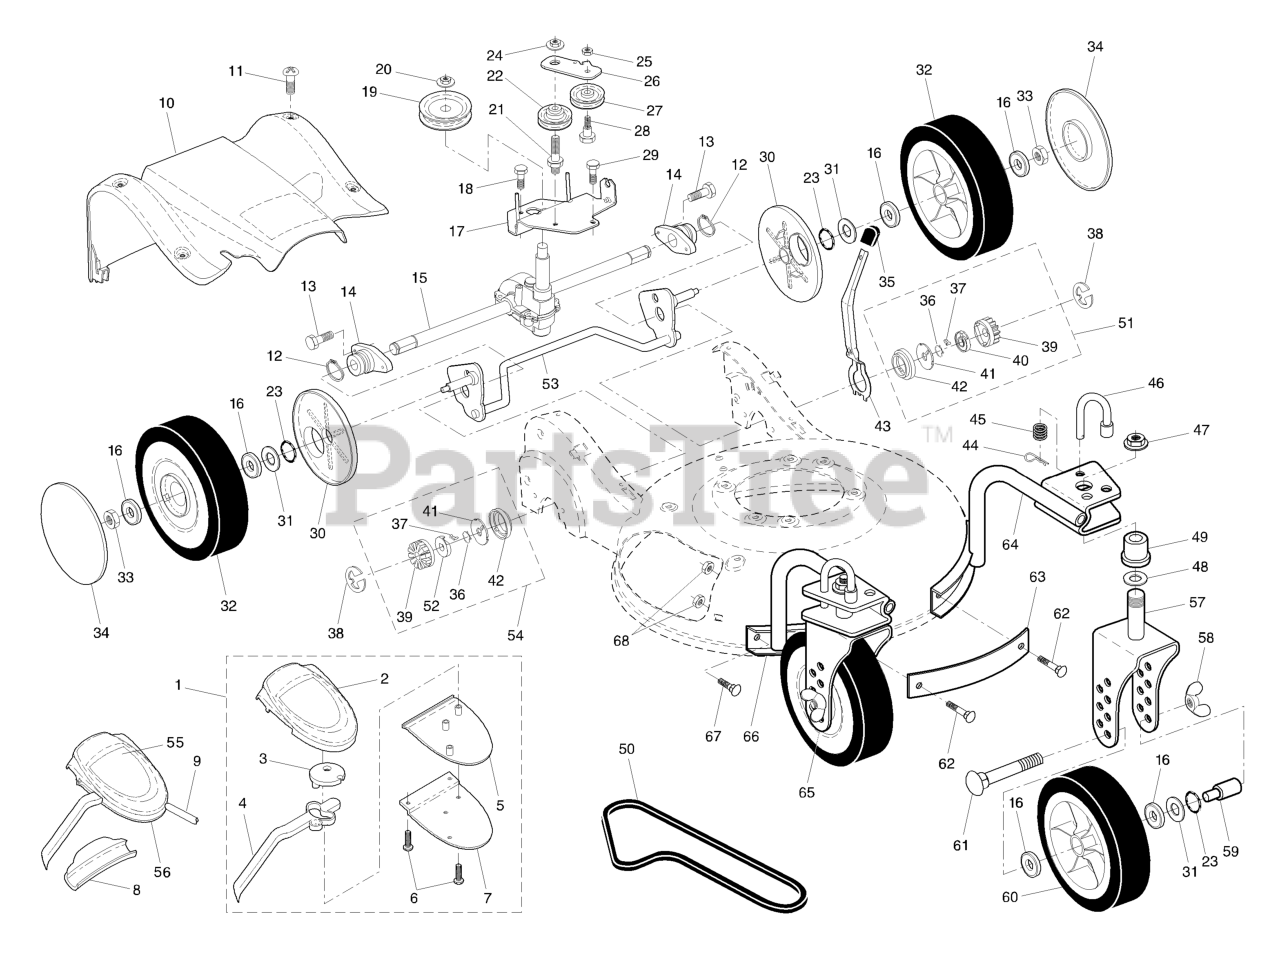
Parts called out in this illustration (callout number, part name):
1	EZ WALK CONTROL
2	COVER, DRIVE CONTROL, TOP
3	PULLEY.CAM.DRIVE.CONTROL.HV
4	LEVER, DRIVE CONTROL
5	COVER, DRIVE CONTROL BOTTOM
6	SCREW, PHILLIPS HEAD 10 X 5/8
7	BRACKET, DRIVE CONTROL
8	EZ WALK SNAP COVER PLATE
9	CABLE, DRIVE CONTROL
10	COVER, REAR DRIVE
11	SCREW
12	RETAINING RING (2 2)(3 2)
13	RP SCREW
14	BEARING.SUPPORT.ASSEM
15	TRANSMISSION.ASM.RGD.EZ.21
16	BEARING.8".WHEEL
17	BRACKET, TRANSMISSION
19	PULLEY HALVES
20	FLANGED LOCKNUT 3/8-16 ZINC
22	PULLEY ASSY
23	O-RING
24	NUT
25	NUT.CENTERLOCK.5/16-
26	BRACKET
27	IDLER PULLEY
28	SHOULDER BOLT
29	SCREW 14-20 X 5/8
30	DUST COVER, WHEEL
31	WASHER.FLAT.1/2
32	WHEEL 9X2.25
33	HEX FLANGE LOCKNT
34	RB HUBCAP.3-SPOKE.SILVER
35	KNOB.SELECTOR.SPRG.H-GRY (2 2)
36	SPRING, TORSION
37	PAWL.DRIVE.21.EZ-WALK
38	E-RING 7/16 RE
39	GEAR, PINION
40	RETAINER.DRIVE.21.EZ-WALK.LT
41	DISC.DRIVE.21.EZ-WALK
42	SEAL.PINION
43	LEVER, SELECTOR
48	WASHER STEEL
49	BUSHING
50	BELT.DRIVE.EZ.WALK.HI-VAC
51	PINION ASSY, LH
52	RETAINER, DRIVE, RH
53	REAR AXLE ASSY.
54	PINION ASSY, RH
57	BRACKET, CASTER
58	NUT.WING.5/16-18.YELLOW
60	WHEEL ASSY, FRONT 9X2
61	CARRIAGE BOLT
63	STRAP, FRONT
64	SUPPORT TUBE ASSY, LH BLK
65	BRACKET CASTER WHEEL, RH
66	SUPPORT TUBE ASSY, RH
68	NUT
